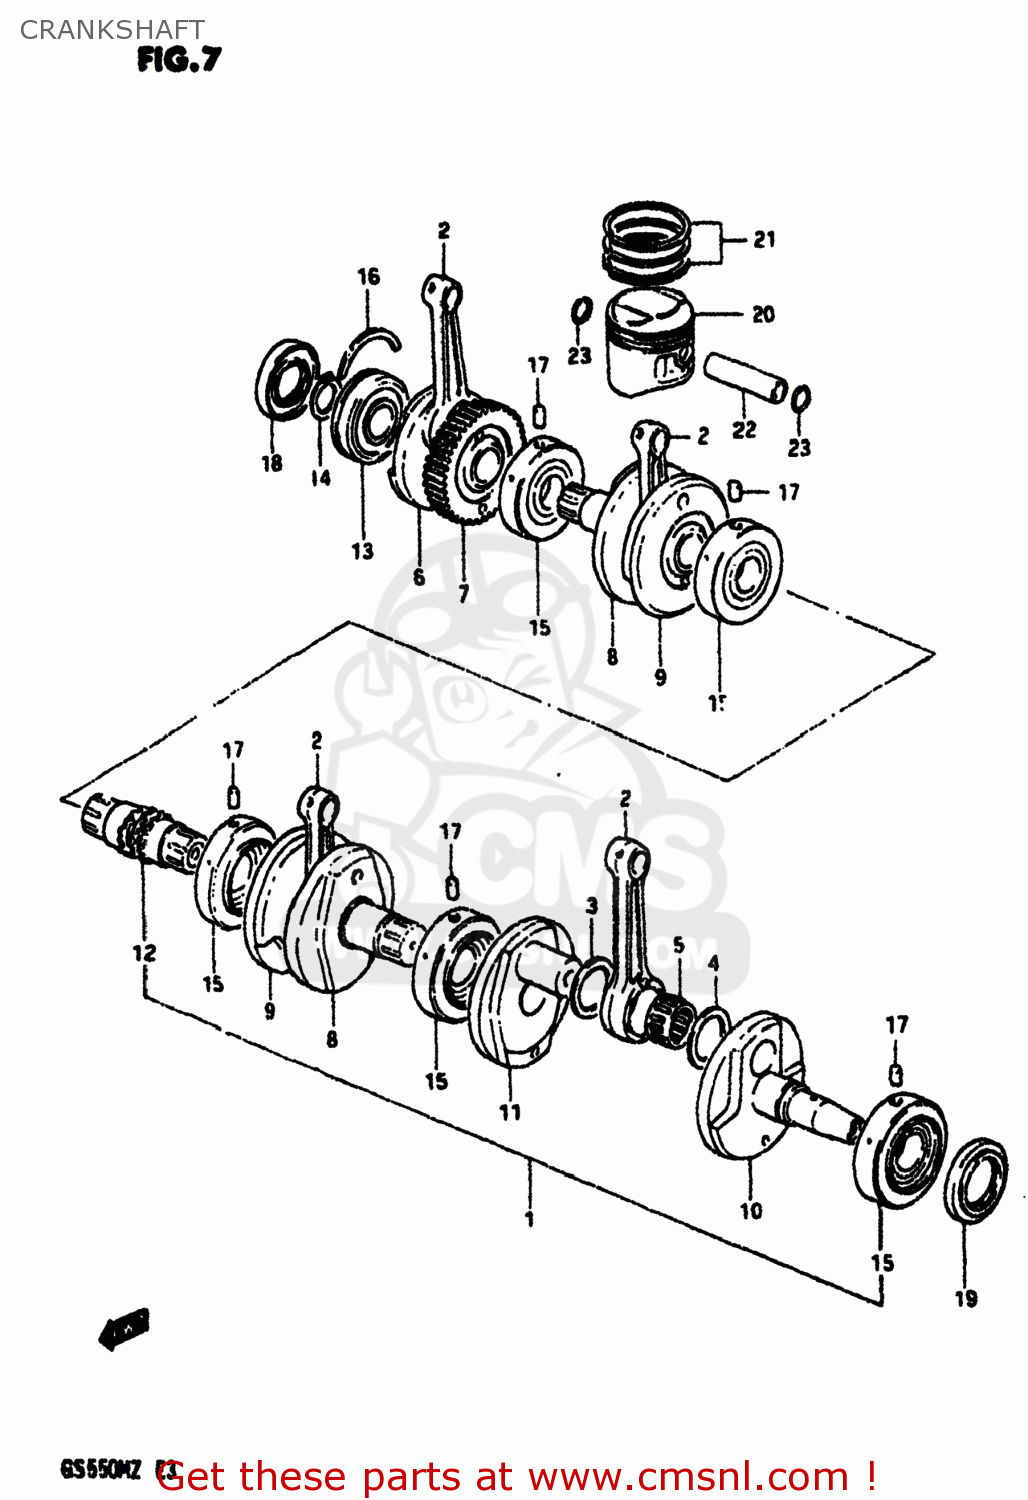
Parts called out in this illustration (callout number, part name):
1	CRANKSHAFT ASSEMBLY
2	ROD,CONNECTING
3	WASHER (28X48X2)
4	WASHER(28X48X1)
5	ROLLER BEARING (28X38X16.8)
6	CRANKSHAFT
7	WEB,CRANK
8	CRANKSHAFT
9	WEB,CRANK,MIDDLE
10	CRANKSHAFT,LEFT
11	WEB,CRANK,LEFT
12	SHAFT,TIMING CHAIN DRIVE
13	BEARING(30X72X19)
14	CIRCLIP,30MM
15	BEARING
16	C RING
17	PIN
18	SEAL,OIL(30X72X11)
19	OIL SEAL
20	PISTON
21	RING SET,PISTON
22	PIN,PISTON 16MM
23	CIRCLIP
